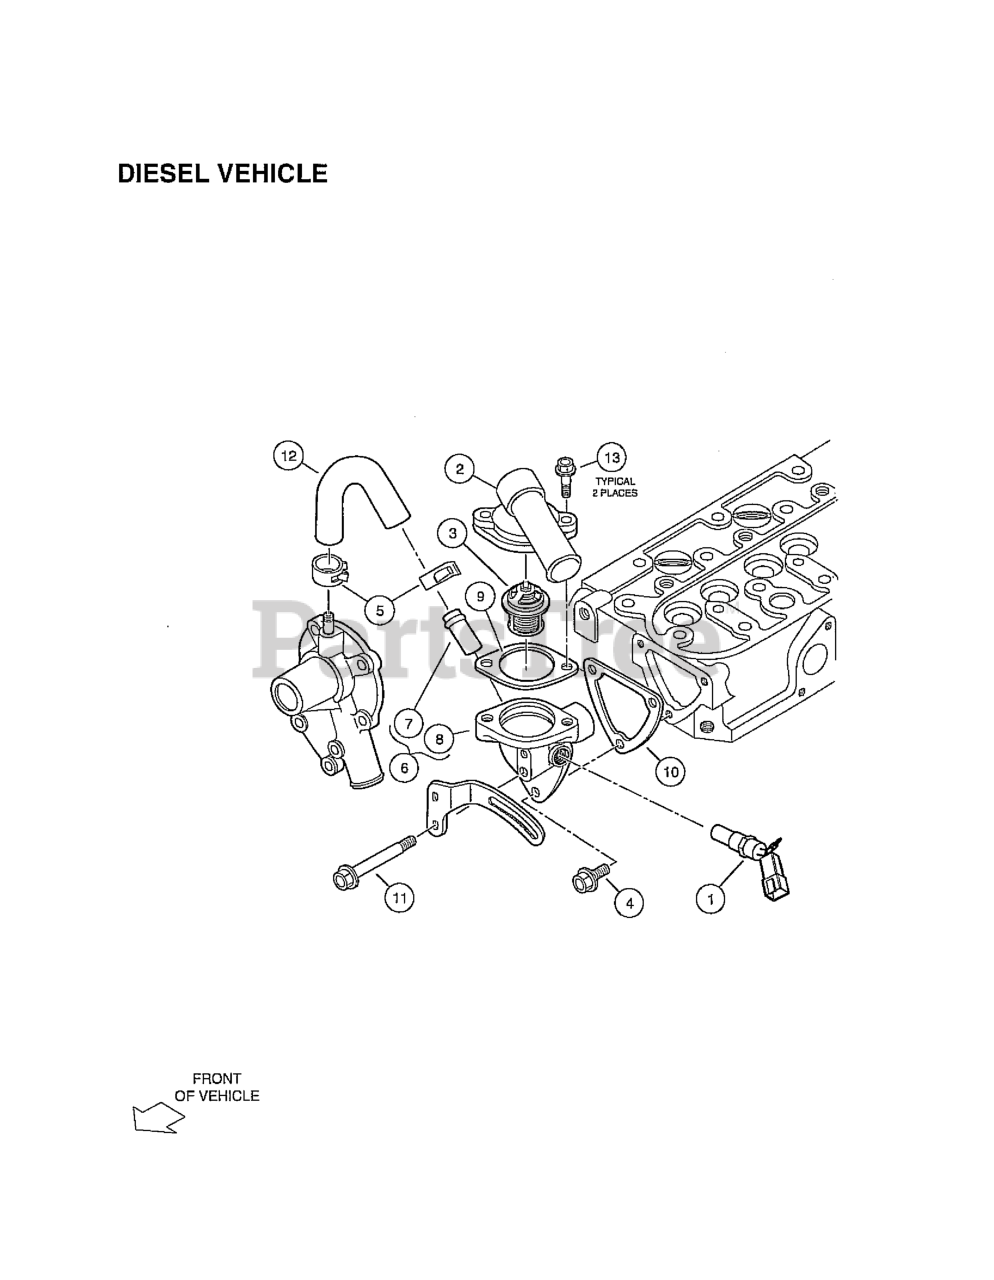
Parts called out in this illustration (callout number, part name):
1	SENSOR, COOLANT TEMP
2	COVER, THERMOSTAT
3	ASSY, THERMOSTAT
4	BOLT, M6X1X20
5	BAND, PIPE
6	COMP, FLANGE WATER
7	PIPE, WATER RETURN, D722
9	GASKET, THERMOSTAT
10	GASKET, WATER FLANGE
11	BOLT, ALT, D722, STAY LOWER
12	PIPE, WATER RETURN, D722
13	Bolt, D722, Thermostat Cover
